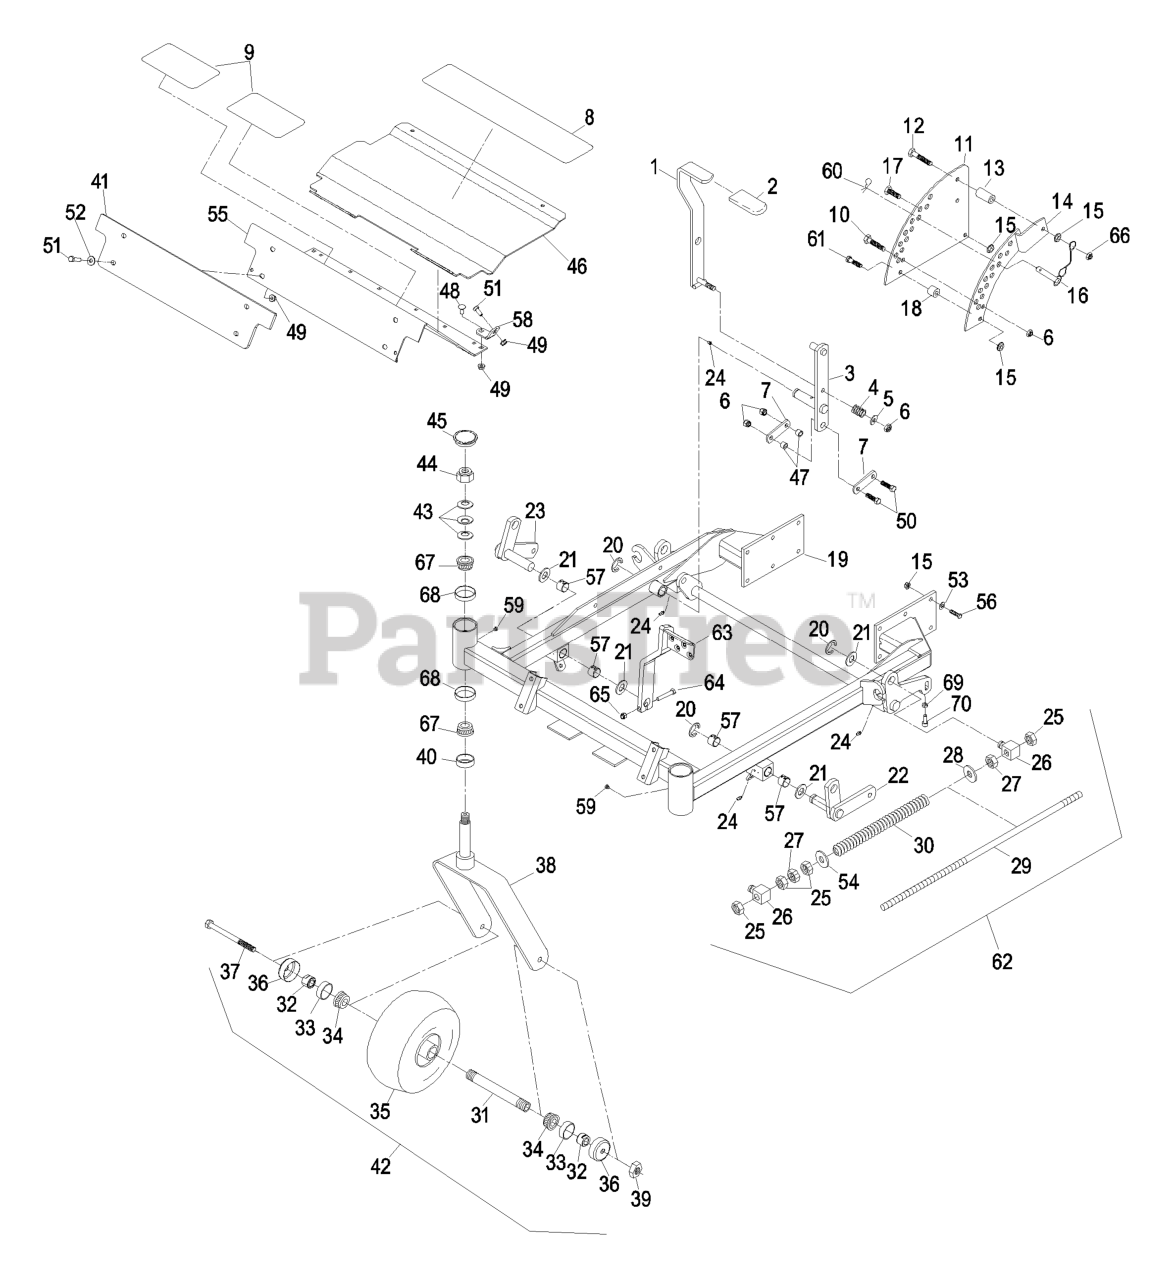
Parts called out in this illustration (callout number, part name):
1	ASM, LIFT LEVER / GRIP
2	GRIP-LEVER, LIFT
3	WLD, DECK LIFT ARM-LHP
4	SPRING-COMPRESSION
5	WASHER-FLAT
6	NUT-LOCK, NI
7	ARM-LIFT, DECK
8	PAD-ANTISKID
9	PAD-ANTI SKID
10	SCREW-HH
11	PLATE-LIFT, DECK
12	SCREW-HH
13	BUSHING-LEVER, LIFT
14	PLATE-LIFT, DECK
15	NUT-HHF, WHIZ
16	PIN-HITCH (W/LANYARD)
17	SCREW-HH
18	BUSHING-LEVER, LIFT
19	KIT, FRONT FRAME-LHP44
20	RING-RETAINING, EXT
21	WASHER-FLAT
22	WLD,SHAFT LH
23	WLD,SHAFT RH
24	FITTING-GREASE
25	NUT-HEX
26	SWIVEL-DECK MOUNT, REAR
27	NUT-JAM
29	ROD-LIFT, DECK
30	SPRING-COMPRESSION
32	SPACER-NUT
33	SEAL-CASTER
34	BEARING-CONE, TAPERED ROLLER
36	GUARD-SEAL
37	SCREW-HH
39	NUT-HEX
40	SEAL-GREASE
42	ASM, WHEEL AND TIRE W/ AX
43	WASHER-BELLVILLE
44	NUT-LOCK, NI
45	CAP-GREASE
47	BUSHING
48	BOLT-CARR
50	SCREW-HH
51	SCREW-HH
52	WASHER-FLAT
53	WASHER-BELLEVILLE
54	WASHER-FLAT
56	SCREW-HH
57	BUSHING,SPRING
58	BRACKET-FLOORPAN
60	PIN-COTTER
61	SCREW-HH
62	FRONT SPRING ASM
64	SCREW-HH
65	NUTTORQUE ZKPLT
66	NUT-LOCK, NI
67	Cone-Bearing Tapered Roller
68	CUP-BEARING
69	NUT-JAM
70	SCREW-HSH
